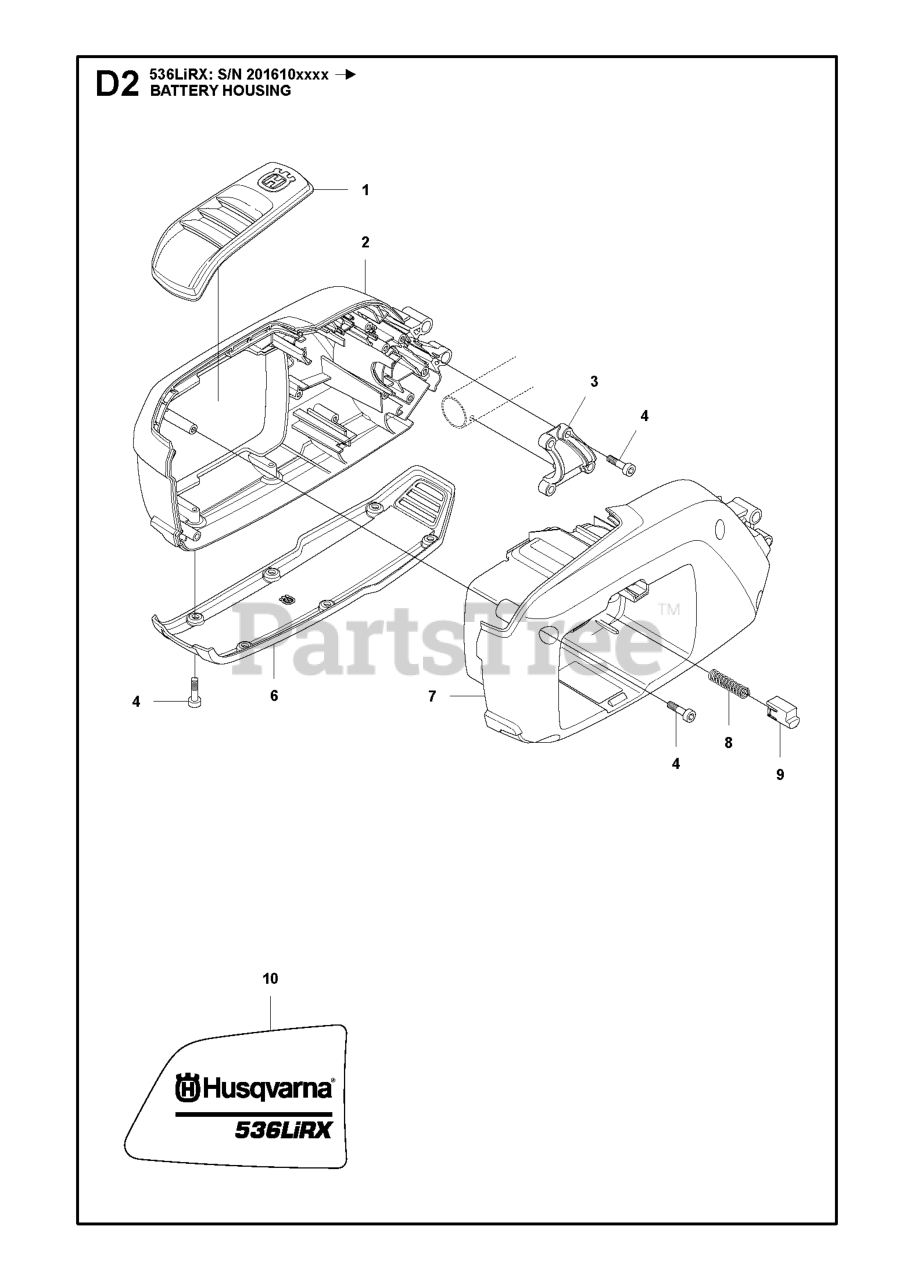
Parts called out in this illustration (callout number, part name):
2	HOUSING LEFT
4	SCREW
6	SKID PLATE
7	HOUSING RIGHT
8	SPRING PUSH OUT
9	PUSH BUTTON
